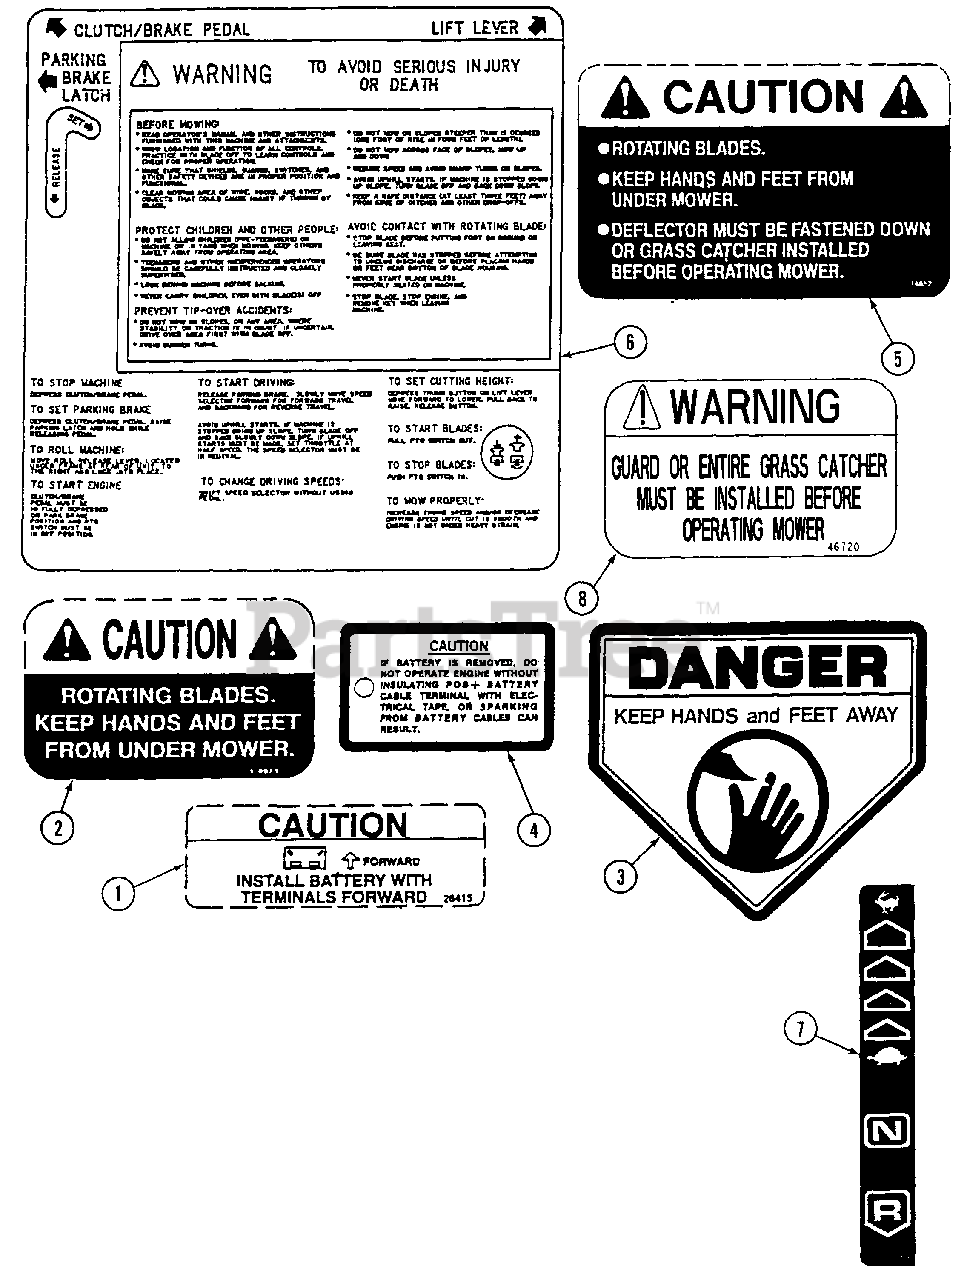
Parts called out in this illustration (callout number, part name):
1	DECAL, Caution
2	DECAL, Caution
3	DECAL, Danger
3	DECAL, Danger, CPSC
4	TAG, Caution
5	DECAL, Caution
6	DECAL, Instruction
7	DECAL, Shift Cover
8	DECAL, Chute/Deflector
